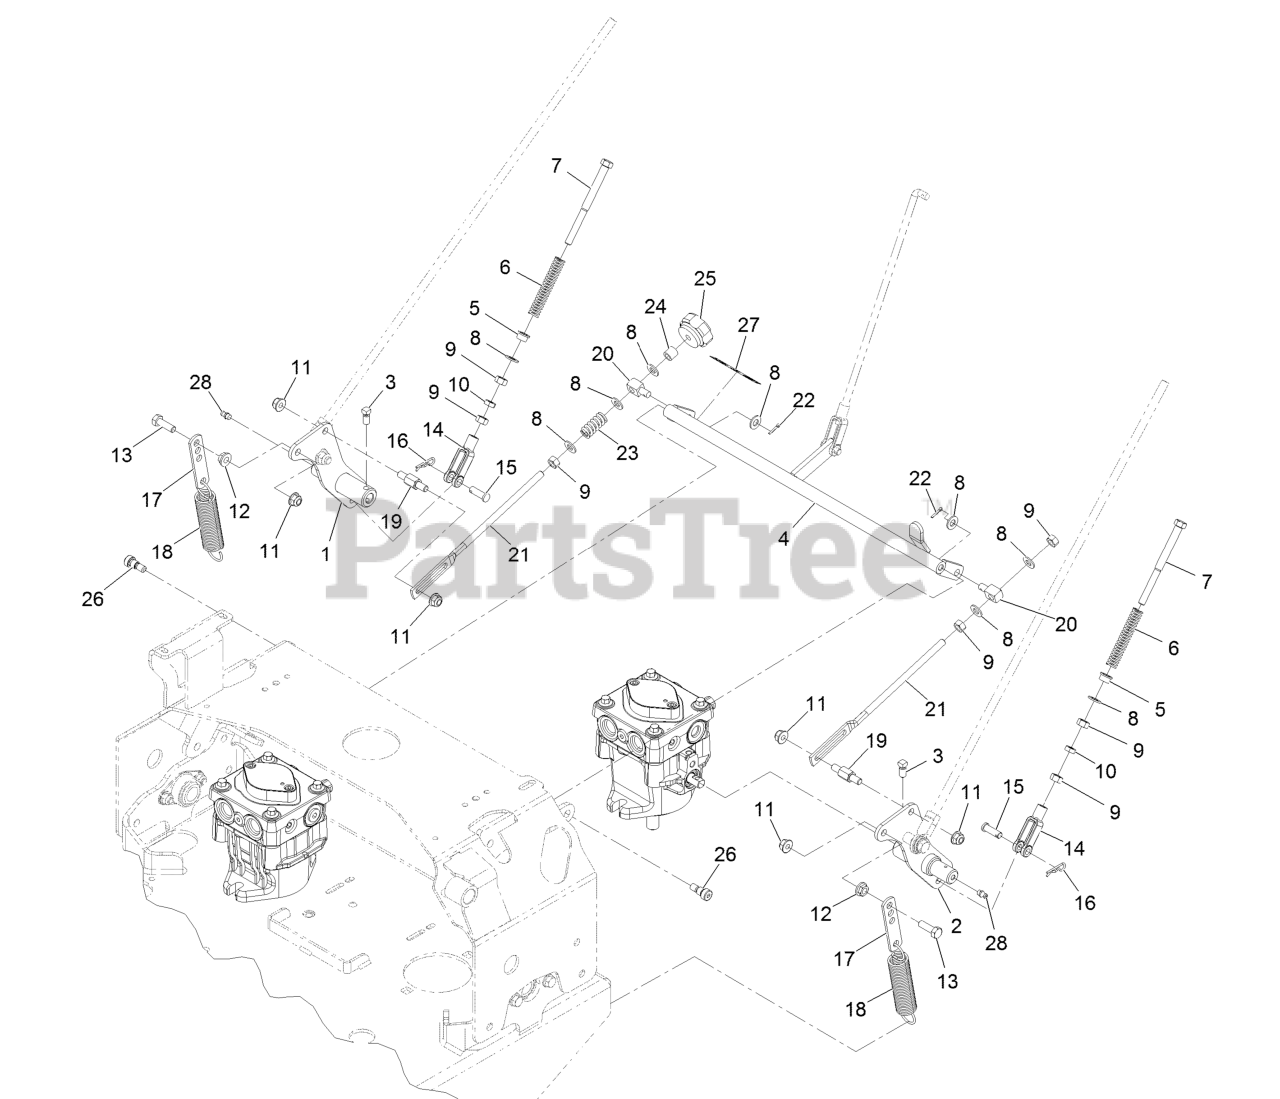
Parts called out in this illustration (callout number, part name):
1	Weld, Motion Control, Rt
2	Weld, Motion Control, Lt
3	Setscrew-5/16-18 X 5/8
4	Weld, Speed Control
5	Bushing-Flanged
6	Spring, Neutral Return
7	Bolt-Neutral Return
8	Washer-5/16 SAE
9	Nut-Hex 5/16-24
10	Nut-Jam 5/16-24
11	Nut-Nyloc 5/16-18 Flg
12	Nut-Whizlock 5/16-18
13	Screw-HH 5/16-18 X 1
14	Yoke-Adjustable
15	Pin-Clevis 5/16 X 1 49/64
16	Hairpin-Cotter
17	Tab-Spring, Extension
19	Pin, Motion Control
20	Swivel-Adjustable, Short
21	Link-Control, Speed
22	Pin-Cotter 3/32 X 1/2
23	Spring-Compression
25	Knob-Tracking
26	Screw-Sh 5/16-18 X 1 3/8
27	Decal-Tracking Adjustment
28	Zerk-1/4-28 Str
